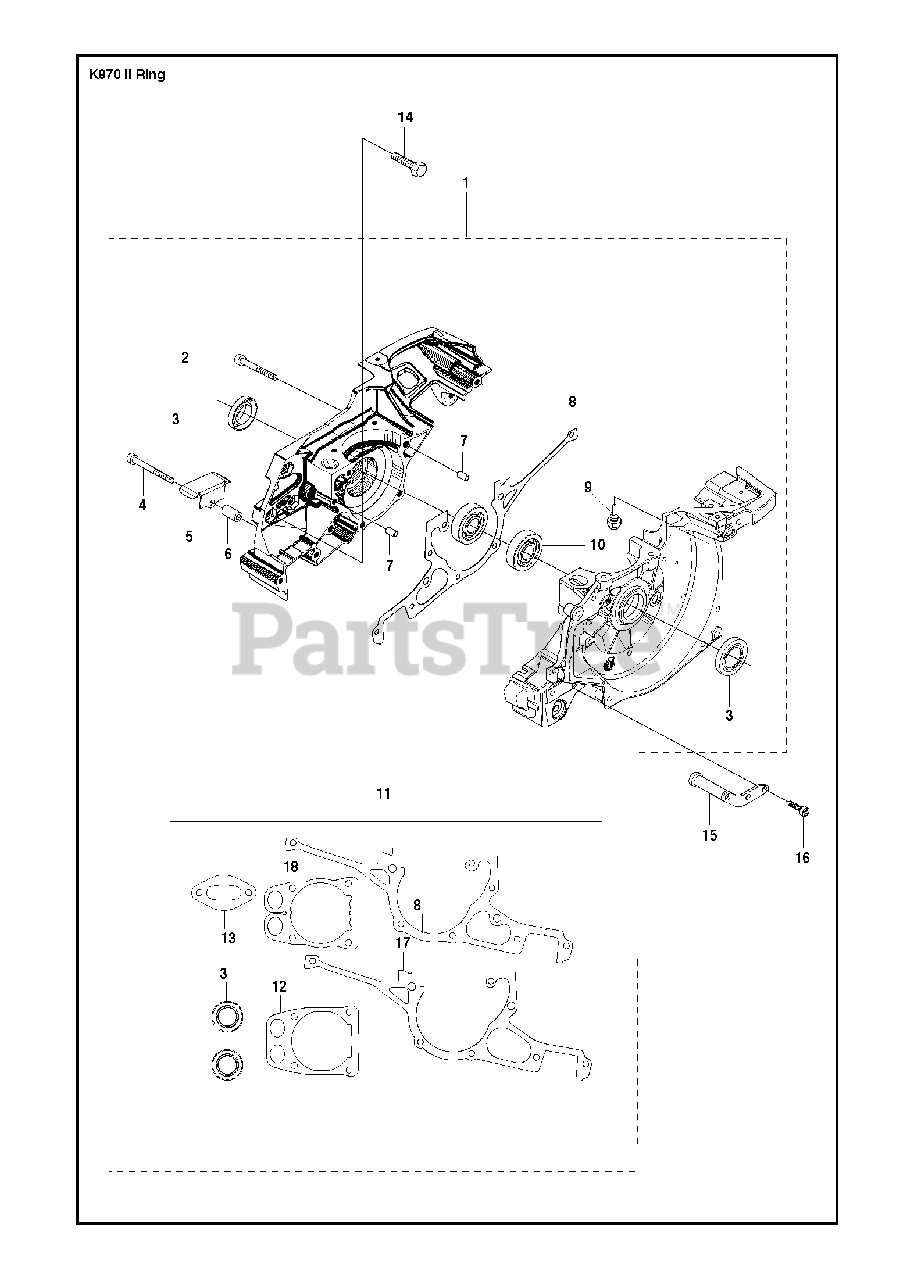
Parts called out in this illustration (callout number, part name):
1	CRANKCASE ASSYIncl. 2 - 11, 14
2	SCREW ITXSCM
3	SEALING RING
4	SCREW ITXSCM
7	GUIDE BUSHING
9	RUBBER BUSHING
10	BALL BEARING
11	GASKET KITIncl. 3, 8, 12 - 13, 17-18
13	GASKET
